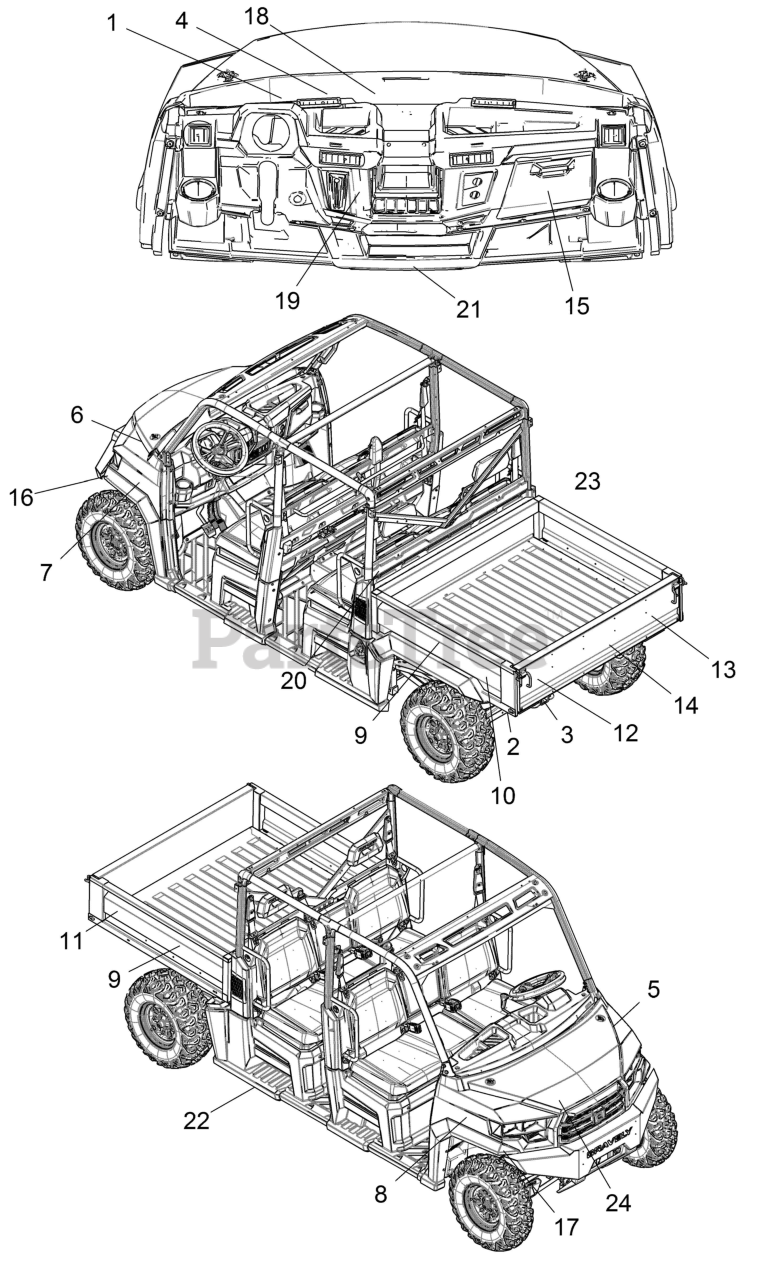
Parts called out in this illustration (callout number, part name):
1	DECAL, AGE WARNING 16
2	DECAL, REFLECTOR RED
3	DECAL-WARNING,TRAILER LOAD
4	LABEL, OPEI COMPLIANCE
5	DECAL, HOOD TOP EFI LH
6	DECAL, HOOD TOP EFI RH
7	DECAL, HOOD SIDE ATLSJSV, LH
8	DECAL, HOOD SIDE ATLSJSV, RH
9	DECAL, BOX SIDE GRAVELY
10	DECAL, BOX,SIDE, 6000, LH
11	DECAL, BOX,SIDE, 6000, RH
12	DECAL, TAILGATE ATLSJSV, LH
13	DECAL, TAILGATE AWD RH
14	DECAL, TAILGATE GRAVELY CENTER
15	DECAL, GLOVEBOX COVER
16	DECAL, REFLECTOR AMBER LH
17	DECAL, REFLECTOR AMBER RH
18	DECAL, WARNING DISC GRAVELY
19	DECAL, CAUTION SHIFT/BRAKE
20	DECAL, ROPS, 6000
21	DECAL,WARNING PASS/TIRE PRESS
22	DECAL NOT A STEP
23	DECAL, WARN, NEVER CARRY FUEL
24	DECAL-COOLANT
